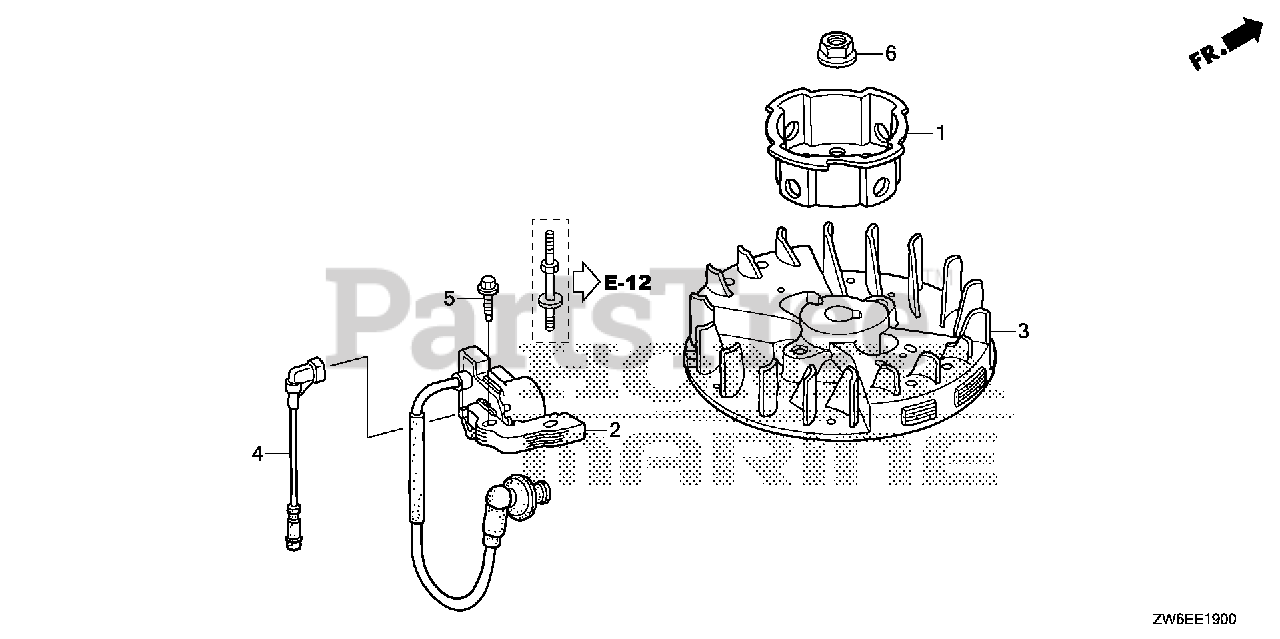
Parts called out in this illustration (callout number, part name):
1	PULLEY, STARTER
2	COIL ASSY., IGNITION
4	WIRE, STOP SWITCH
5	BOLT, FLANGE (5X20) (CT200)
6	NUT, FLANGE (10MM)
